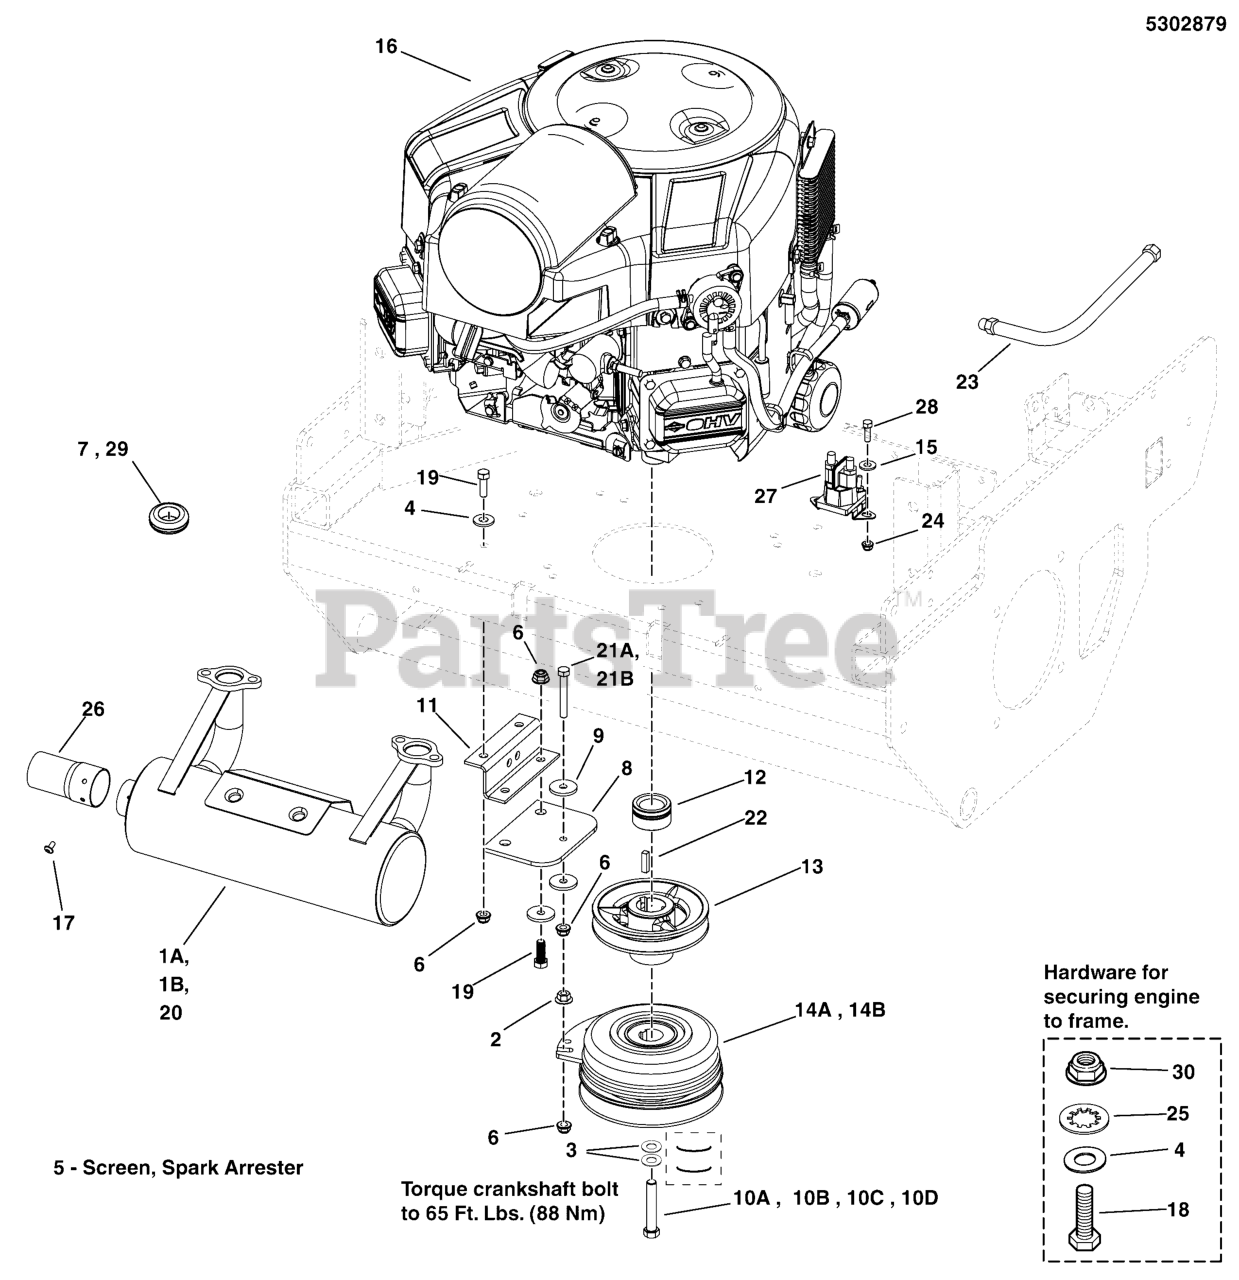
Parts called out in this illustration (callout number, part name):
2	NUT, 5/16-18 HEX SERRATED FLANGE (LARGE)
3	BELLEVILLE WASHER 1.1875 X .442 X .089
4	WASHER, 5/16" SAE
6	NUT, 5/16-18 HEX NYLOCK FLANGE
7	GROMMET, 7/8
8	CLUTCH ANCHOR PAD
9	WASHER, .34 X 1.25 X 10 GA
11	ANCHOR, CLUTCH - BLK
12	SPACER, 1.13 X 1.75 X 1.35, YZ
13	PULLEY, 4.75 OD X 1-1/8 BORE, BC-48
15	WASHER, 1/4 SAE
16	ENGINE, B&S, COMM TURF
17	SCREW,SELF-TAP,#8-32 X 3/8,WASH HEX, CZ
18	BOLT, 5/16-24 X 1-3/4, GD8
19	BOLT, 5/16-18 X 1 GD5 YZ
20	MUFFLER, RIGHT OUTLET ASSY
22	KEY, 1/4 SQ. X 1.25
23	HOSE, OIL DRAIN
24	NUT, 1/4-20 HEX SERR. FLANGE
25	WASHER, 5/16 INT. TOOTH LOCK
26	EXTENSION, TAILPIPE, 3" - BLACK
27	SOLENOID-4 POLE 12 VOLT DC (TROMBETTA)
28	HHCS, 1/4-20 X 0.625, GR5, ZINC/CLEAR
29	GROMMET, 7/8"ID, 1/4" THICK STK
30	NUT, 5/16-24, NYLOCK FLANGE, GD8, CZ
